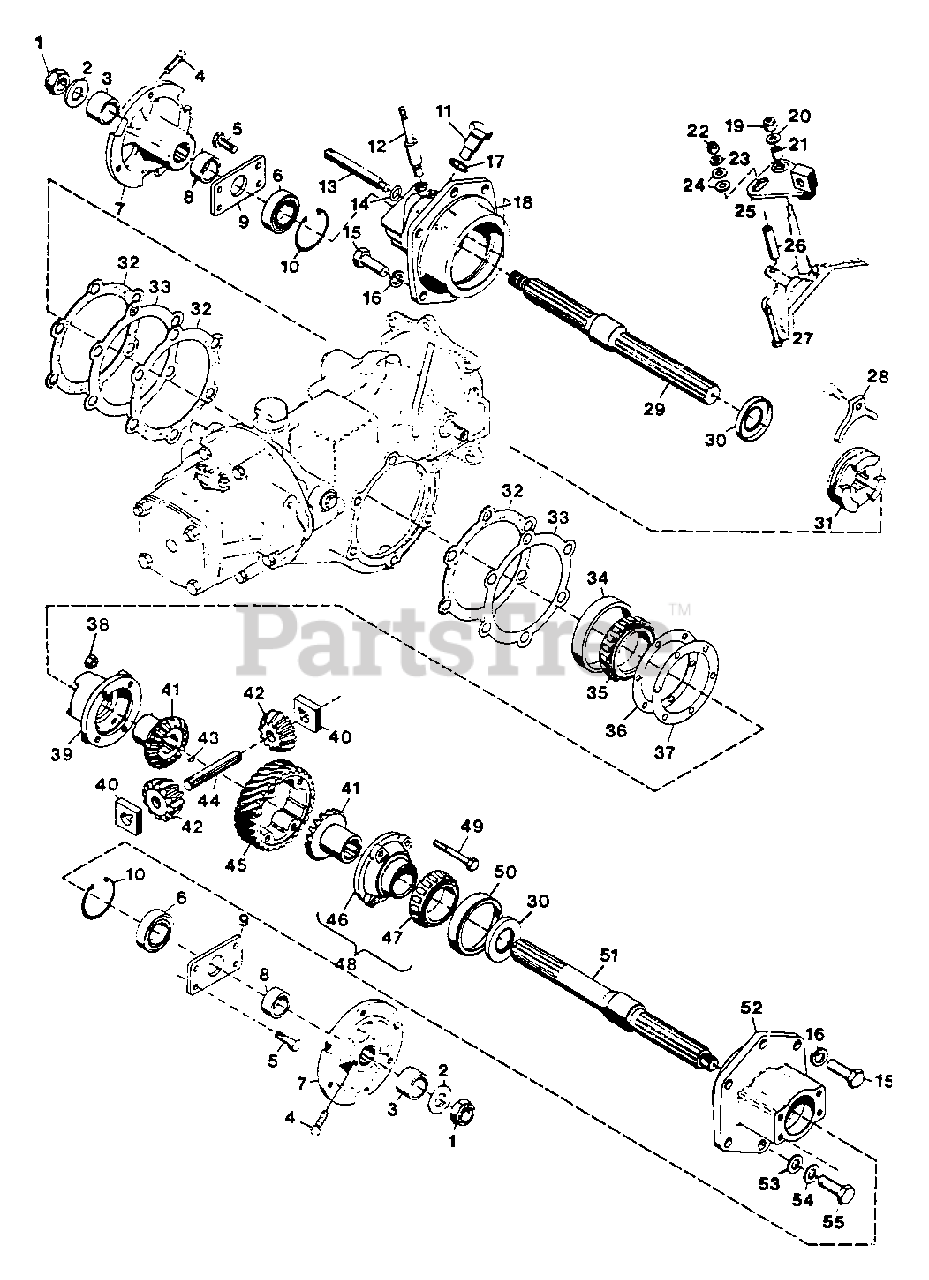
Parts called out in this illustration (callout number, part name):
1	Nut, Hex 3/4-10 Light Thin
2	Washer, Flat .812x1.469x.134
3	Spacer
4	Screw, Set 7/16-14x1.00 SQHCP
5	Bolt. Hex 3/8-16x.750
6	Bearing, Ball 1.000x2.000x.562
7	Hub, Wheel
8	Spacer
9	Plate, End
10	Ring, Retaining 2.000 Bore
11	Bolt, Stationary Clutch
12	Pivot, Stationary
13	Pin, Clutch Sliding
14	O-Ring, .438x.625x.094
15	Bolt, Hex 1/2-13x1
16	Washer, Lock 1/2 Reg.
17	Washer, Oil Strainer Nut
18	Housing, Axle 2-Speed
19	Nut, Lock 5/16-18
20	Washer, Flat .344x.688x.065
21	Bushing, Nylon .375x.503x.875
22	Nut, Lock 1/4-20
23	Washer, Flat .281 x.625x.065
24	Washer, Flat .406x.812x.065
25	Weldment, Arm Shifter
26	Bushing
27	Bolt, 1/4-20x2.25 Gr. 8 PHD
28	Yoke. Shifting
29	Axle, Straight Differential Lock
30	Seal, Oil 1.188x2.000x.250
31	Clutch, Sliding Differential Lock
32	Gasket, Axle Housing
33	Shim, Axle Housing .005
34	Cup, Roller Bearing
35	Cone, Roller Bearing
36	Shim, Clutch Worm Gear .020
37	Shim, Clutch Worm Gear .005
38	Nut, Lock 5/16-24
39	Housing, Differential Lock
40	Block, Drive
41	Gear, Differential Bevel
42	Gear, Spider Bevel
43	Key, Woodruff .125x.375 Hard
44	Pin, Spider Pinion
45	Gear, 6 Lead Worm
46	Housing, Differential
47	Cone, Roller Bearing
48	Assembly, Differential Housing
49	Bolt, Hex 5/16-24x3.00
50	Cup, Roller Bearing
51	Axle, Straight
52	Housing, Axle
53	Seal, Oil Drain
54	Washer, Flat .531x1.062x.095
55	Bolt, Hex 1/2-13x1 Nylon Insert
NS	Decal, Differential Lock French
